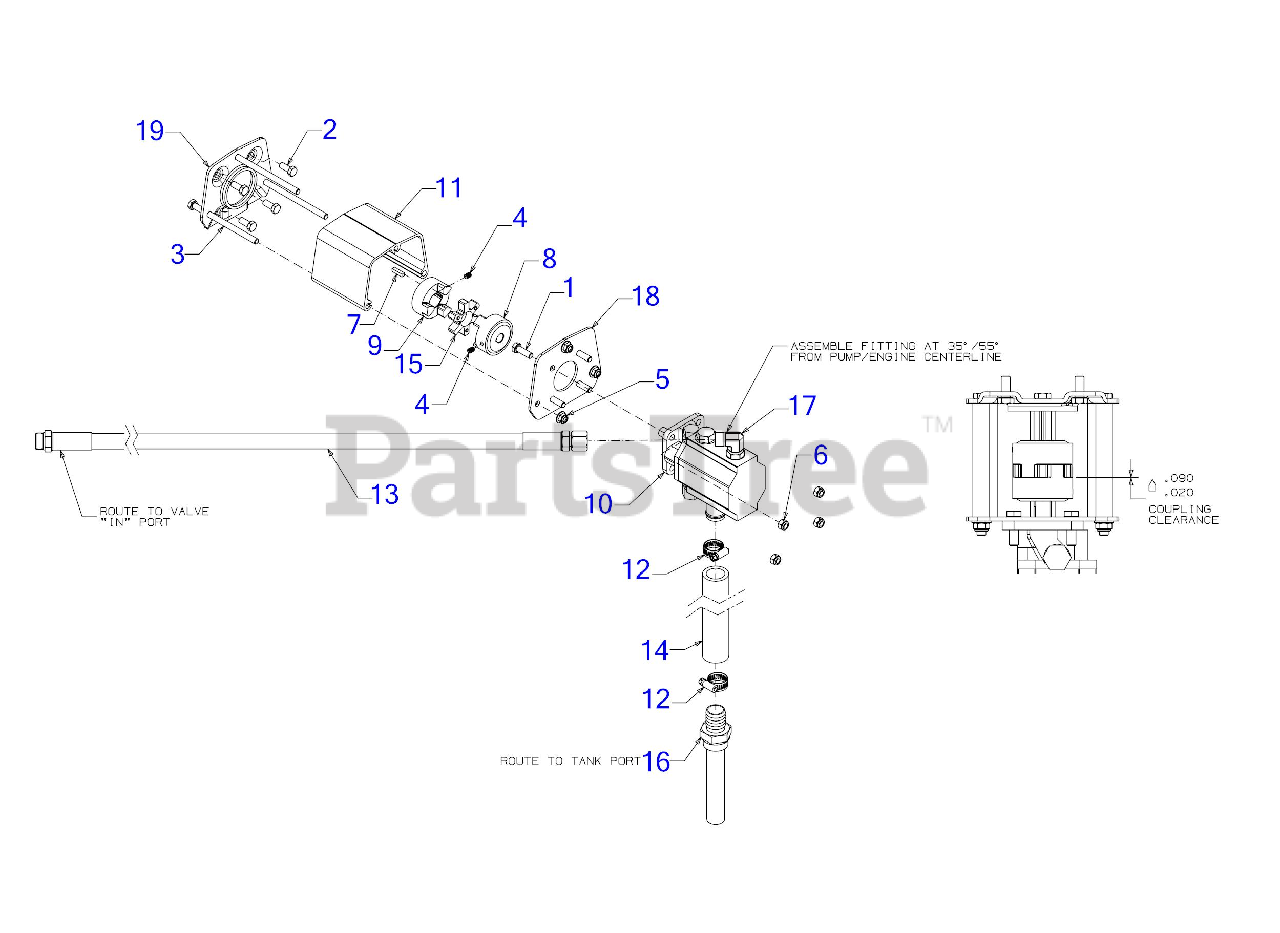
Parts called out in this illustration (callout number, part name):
1	SCREW 5/16-18 x 1.0 GR5
2	SCREW 5/16-24 x .750 GR5
3	SCREW 5/16-18 x 4.750 GR5
4	SCREW 1/4-20 x .38
5	FLANGE LOCK NUT 5/16-18
6	HEX NUT
7	SQUARE KEY 3/16 x .7
8	LOGSPLITTER COUPLING .500
9	LOGSPLITTER COUPLING .875
11	COUPLING SHIELD
12	HOSE CLAMP-5/8
13	48" HYDRAULIC HOSE
14	SUCTION HOSE
15	SPIDER COUPLING BUSHING
16	INLET FILTER
17	HYDRAULIC FITTING
18	SUPPORT BRACKET
